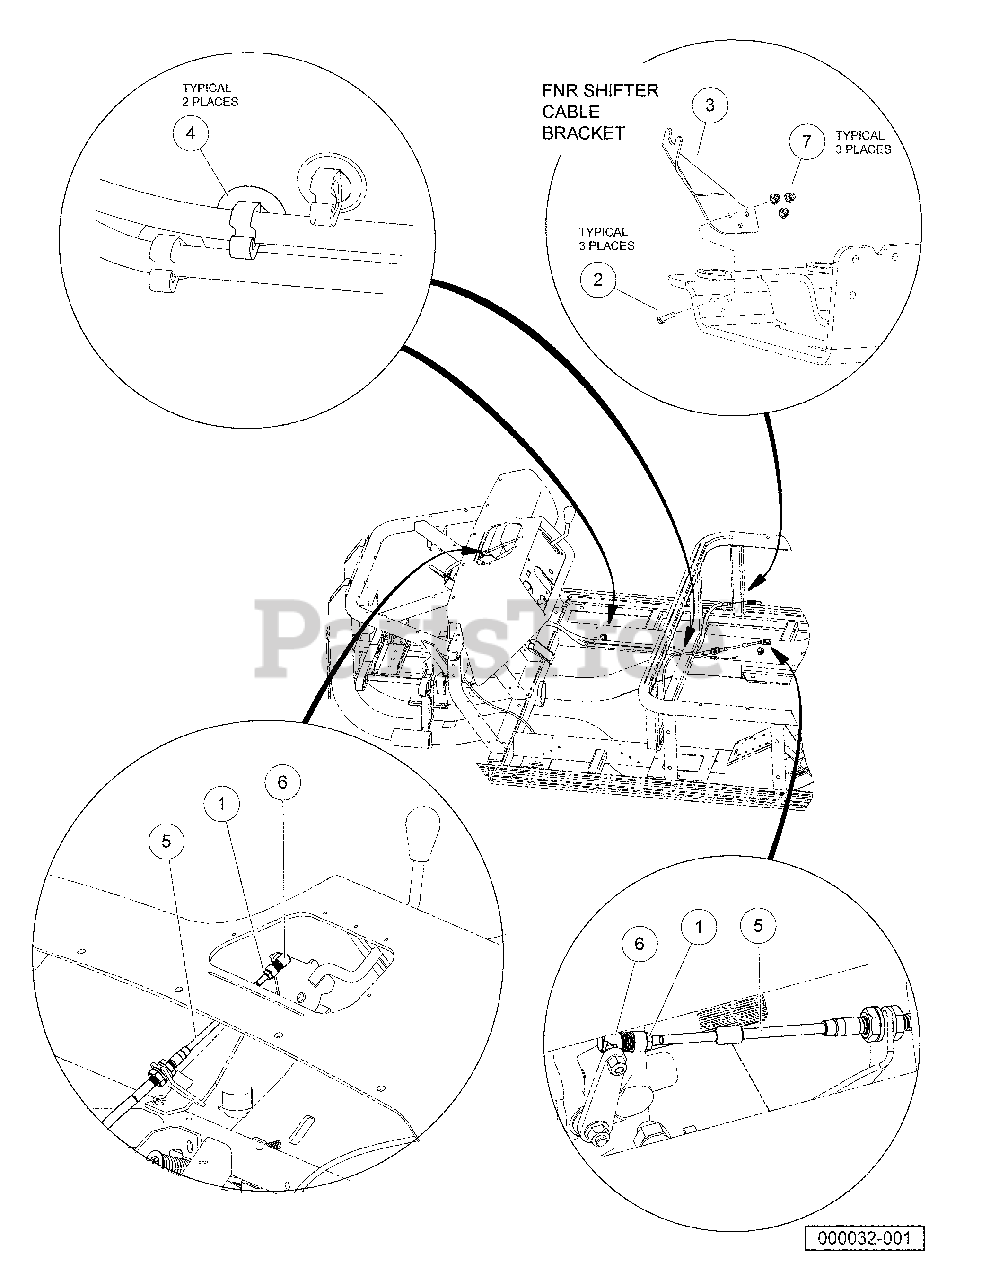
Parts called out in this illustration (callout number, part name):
1	Nut, 1/4-28 Hex Jam
2	Screw, M6-1.00 X 25mm Hex Cap
3	Bracket, FNR Trans Cable
4	Clip, Brake Line
5	Cable, Transmission Shift
6	Joint, Ball, .346 Dia
7	Nut Flg, M6 X 1.0 Nylon
